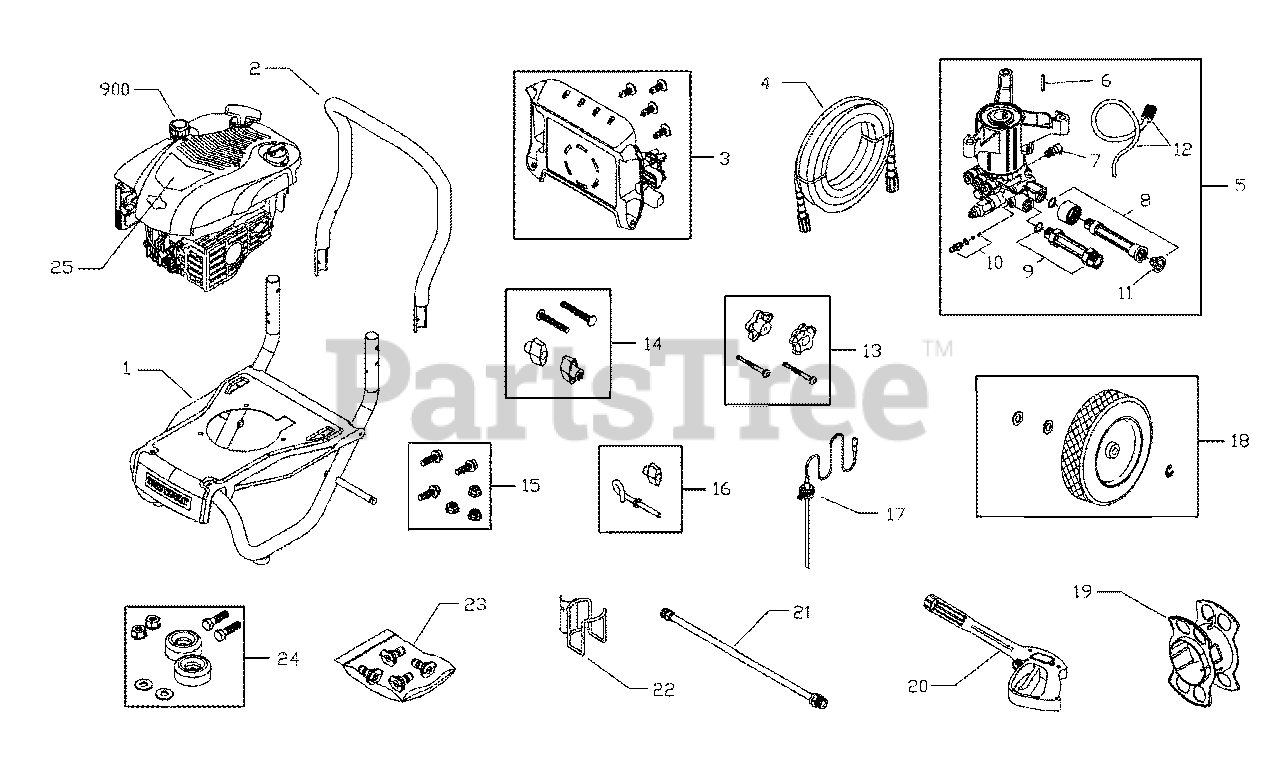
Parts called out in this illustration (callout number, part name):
1	BASE, w/Vib Mounts
2	HANDLE
3	KIT, Billboard w/Clips & Decals
4	HOSE
5	PUMP, Complete
7	Valve, Thermal Relief
8	Kit, Water Inlet
9	Kit, Water Outlet
12	Kit, Chemical Hose
15	KIT, Pump Mounting Hardware
16	KIT, Rope Guide
20	GUN
21	EXTENSION, QC
23	KIT, Spray Tips
24	KIT, Vibration Mount
